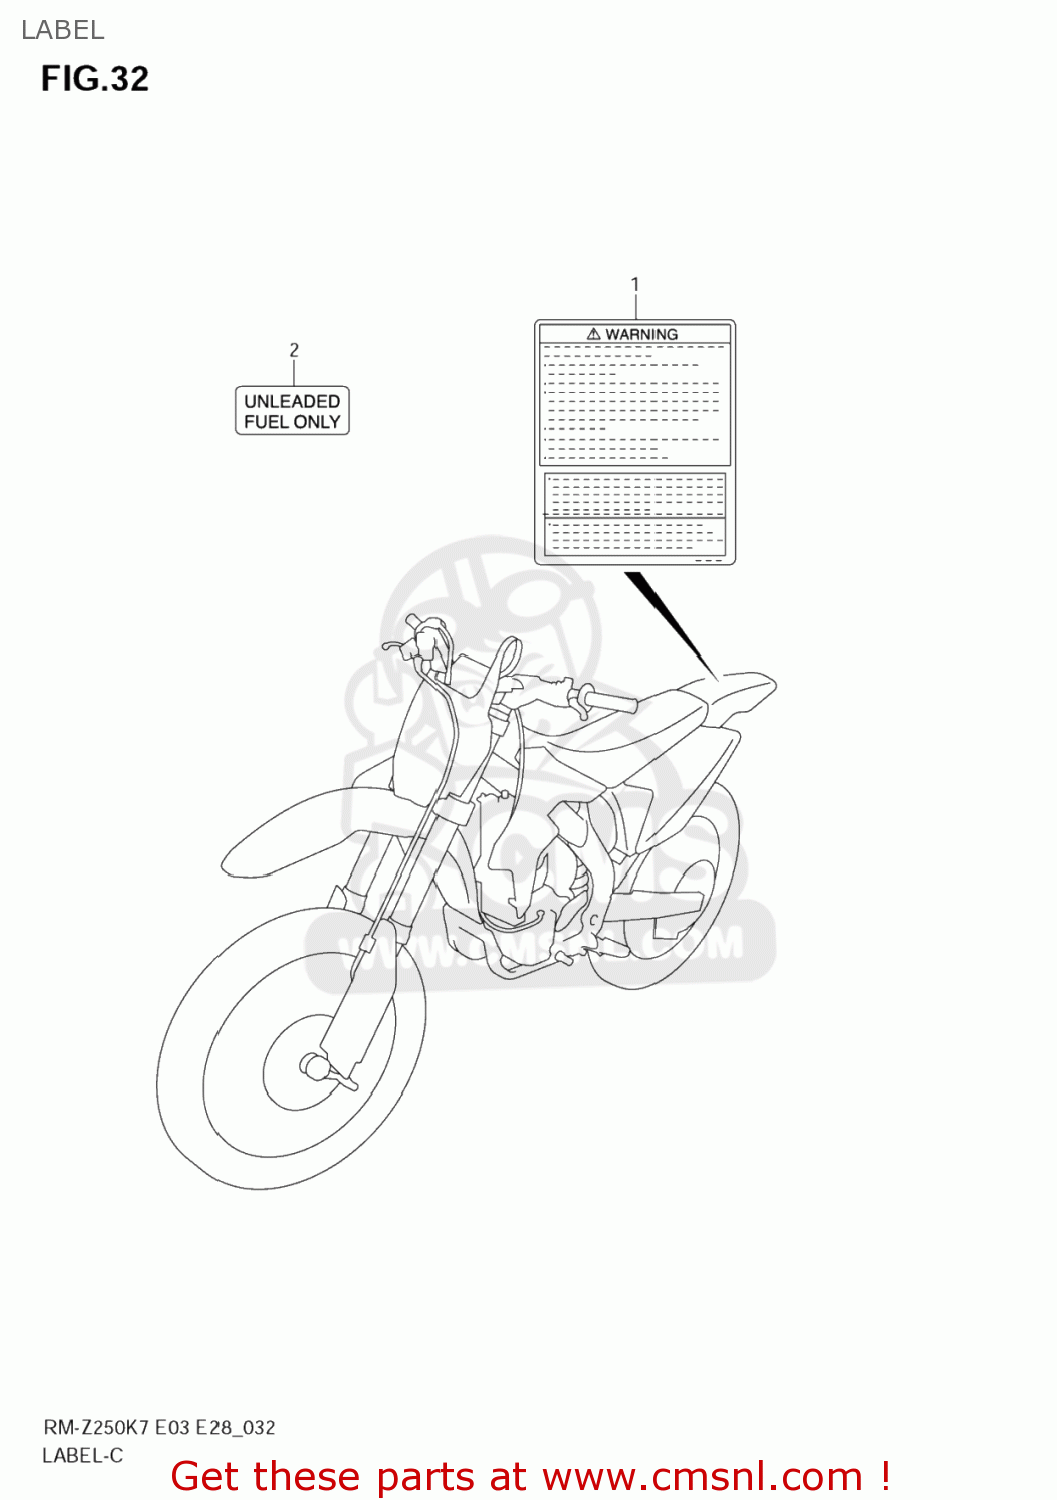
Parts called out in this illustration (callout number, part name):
1	LABEL,WARNING
2	LABEL,UNLEADED FUEL
3	MANUAL,OWNER'S
